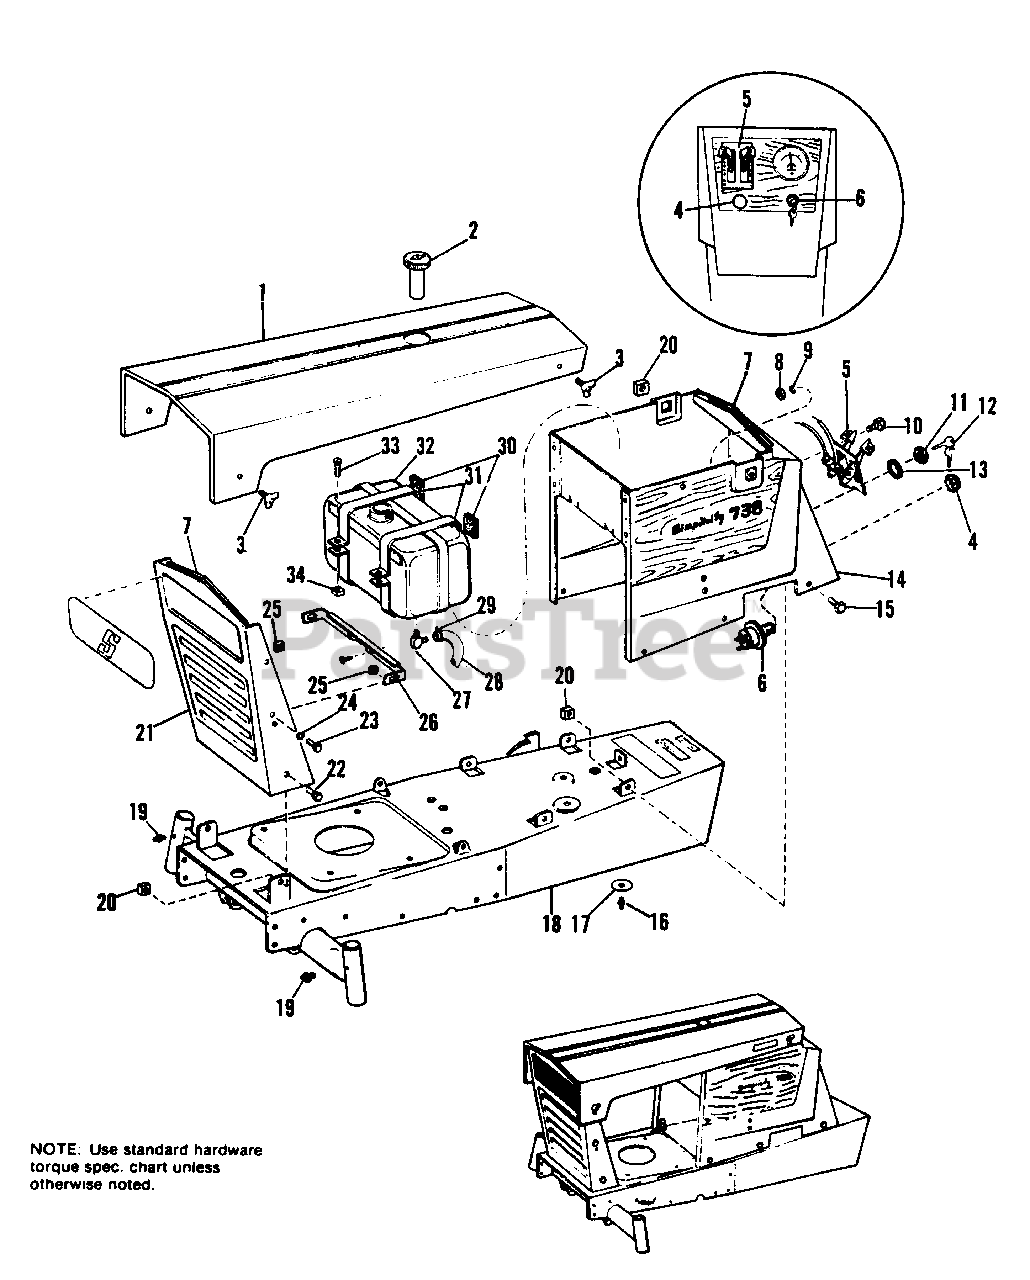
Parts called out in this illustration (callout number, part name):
2	CAP, Fuel Tank
3	SCREW, Thumb, 5/16-18 x 3/4
4	BUTTON, Plug
5	CONTROL, Dual
6	SWITCH, Ignition
7	DAMPENER, Vibration
8	NUT, Hex, Full, 1/4-20
9	LOCKWASHER, 1/4
10	CAPSCREW, Hex Hd., 1/4-20 x 1-1/2
11	NUT, Special
13	LOCKWASHER. Int., 9/16
14	DASH ASSY.
15	SCREW, Hex, Taptite, 1/4-20 x 3/8
16	FITTING, Grease
17	WASHER, Plain, #10
18	FRAME ASSY.
19	FITTING, Grease
20	NUT, Retainer
21	GRILLE ASSY.
22	SCREW, Hex, Taptite, 5/16-18 x 3/8
23	CAPSCREW, Hex Hd., 5/16-18 x 5/8
24	LOCKWASHER, 5/16
25	NUT, Retainer
26	GRILLE, Support
27	VALVE, Shutoff (990780 & 990904 Only)
29	CLAMP, Hose
30	GASKET, Felt
31	STRAP, Tank
32	TANK, Fuel
33	SCREW, Machine, Fillister Hd., 1/4-20 x 1-3/4
34	NUT, Square, 1/4-20
